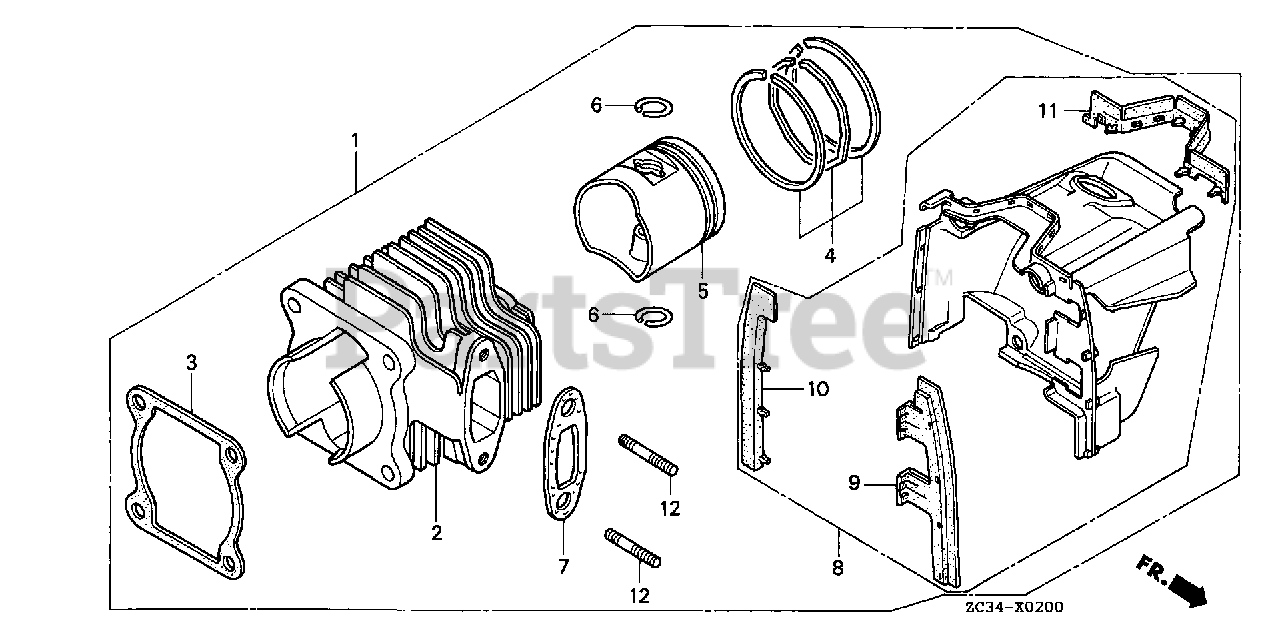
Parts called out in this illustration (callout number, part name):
1	CYLINDER KIT
3	GASKET, CYLINDER
4	RING SET, PISTON
6	CLIP, PISTON PIN
7	GASKET, EX. PIPE
8	SHROUD ASSY.
9	R. RUBBER, SHROUD SEALING
10	L. RUBBER, SHROUD SEALING
11	RUBBER, SHROUD SEALING (UPPER)
12	BOLT, STUD (5X16)
